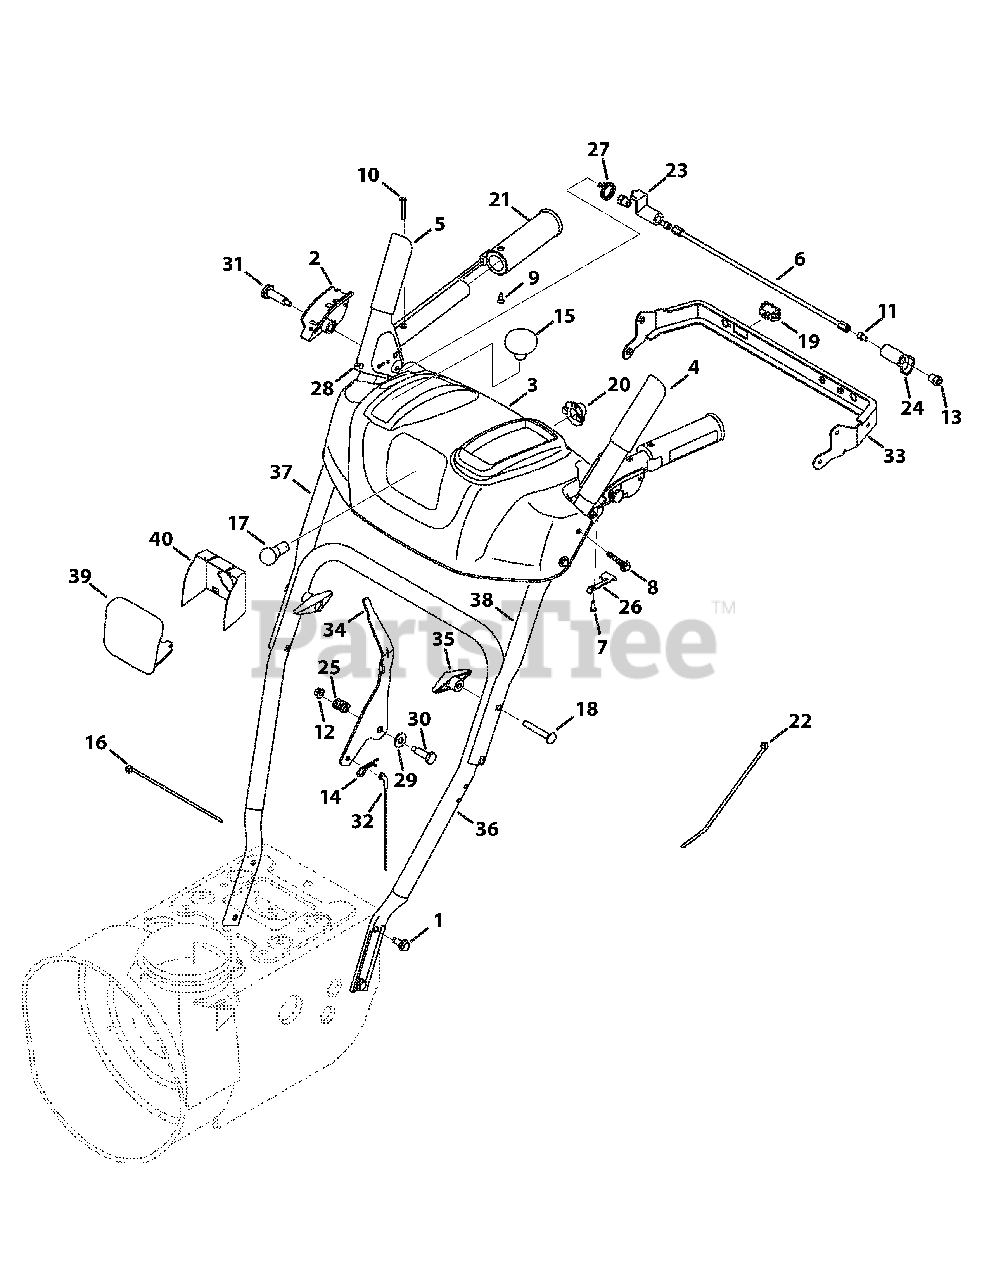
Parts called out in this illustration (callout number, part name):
1	Screw, Taptite, 5/16-18 x .750
2	Clutch Lock, RH
2	Clutch Lock, LH
3	Handle Panel, includes 39 & 40
4	Auger Engage, Black
5	Drive Engage, Black
6	Pivot Rod
7	Screw, Plastite, 8-16 x .50
8	Screw, Taptite, 1/4-20 x 1.625
9	Screw, 10-16 x 0.625
10	Screw, 10-24 x 1.375
11	Screw, 1/4-20 x .50
12	Nut, Flangelock, 1/4-20
13	Nut, Hex, 1/4-20
14	Click Pin, .092 x 1.64
15	Shift Knob
16	Cable Tie, 7"
17	Lamp, 12.8V, 357cc Engine
17	Lamp, 179cc & 208cc Engines
18	Screw, Carriage, 5/16-18 x 2.25
19	Heated Grip Switch
20	Lamp Socket
21	Heated Grip
22	Cable Tie, Push Mount
23	Plate, Lock
24	Cam, Clutch Lock
25	Compression Spring, .39 x .60 x .88
26	Clutch Lock Spring
27	Torsion Spring, 0.8156 x .3038
28	Rubber Bumper
29	Washer, Flat, .385 x .87
30	Screw, Shield, .374 x 1.05
31	Screw, Shoulder, .437 x 1.345 x 1/4-20
32	Speed Selector Cable
33	Panel Bracket
34	Shift Lever
35	Wing Knob
36	Lower Handle
37	Upper RH Handle
38	Upper LH Handle
39	Lens Panel
40	Lens Label
